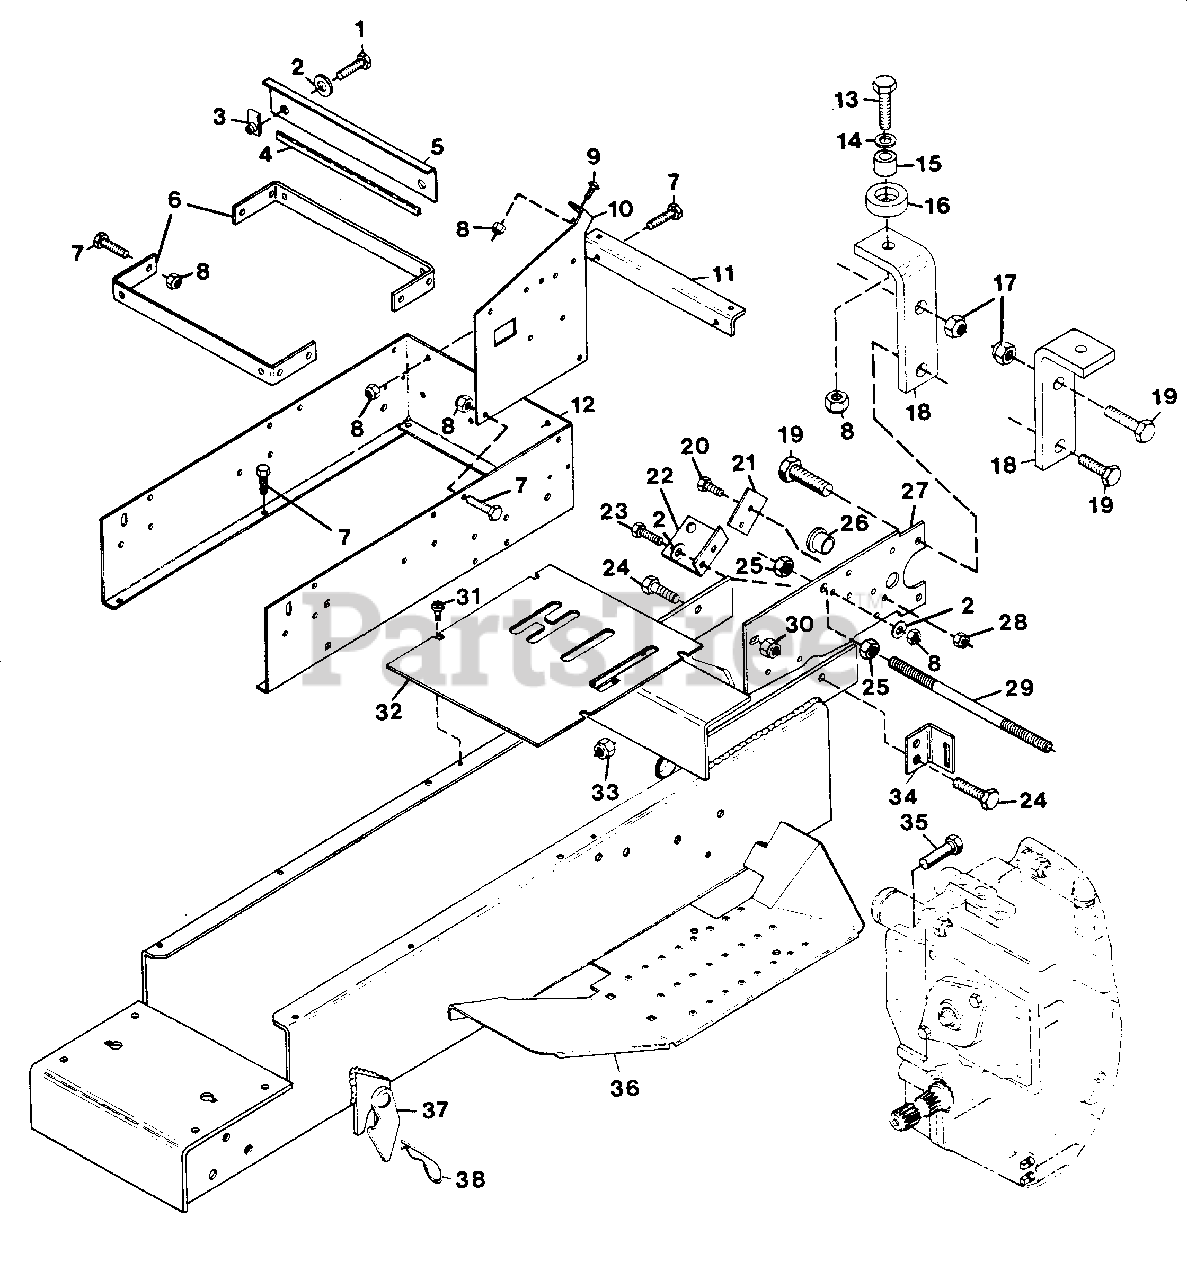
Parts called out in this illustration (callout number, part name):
1	BOLT, HEX 1/4-20X.875
2	WASHER, FLAT .281X.625X.065
3	NUT, RETAINER
4	MOULDING
5	BRACKET, FORWARD TANK
6	BRACKET, FUEL TANK
7	BOLT, HEX 1/4-20X.75
8	NUT, LOCK 1/4-20
9	SCREW, MACHINE 1/4-20X.75 PHD
10	BRACE, INSTRUMENT PANEL L.H.
10	BRACE, INSTRUMENT PANEL R.H.
11	BRACKET, INSTRUMENT PANEL
12	SUPPORT, INSTRUMENT PANEL
13	BOLT, HEX 1/4-20X1.25
14	WASHER, FLAT .312X.734X.065
15	BUSHING, .259X.375X.25
16	BUMPER, SEAT
17	NUT, LOCK 1/2-13
18	BRACKET, REAR HITCH
19	BOLT, HEX 1/2-13X1.50
20	BOLT, HEX 5/16-18X.75
21	BRACKET, BUSHING LOCK
22	BRACKET, INTERLOCK SWITCH
23	BOLT, HEX 1/4-20X1.00
24	BOLT, HEX 3/8-16X1.50
25	NUT, HEX 1/2-13
26	BUSHING, NYLON .76X1.00X.76 FLG.
27	PLATE, FWD-REV MOUNTING
28	NUT, LOCK 5/16-18
29	ROD, FRAME EXTENSION BRACE
30	NUT, LOCK 3/8-16
31	SCREW, TAPPING 1/4-20X.625 PHD
32	PLATE, HYDRAULIC CONTROL COVER
33	NUT, RIM
34	BRACKET, FENDER HOLD-UP
35	BOLT, HEX 1/2-20X1.50
36	WELDMENT, FRAME
37	WELDMENT, MOWER BRACKET R.H.
37	WELDMENT, MOWER BRACKET L.H.
38	PIN, HAIR
